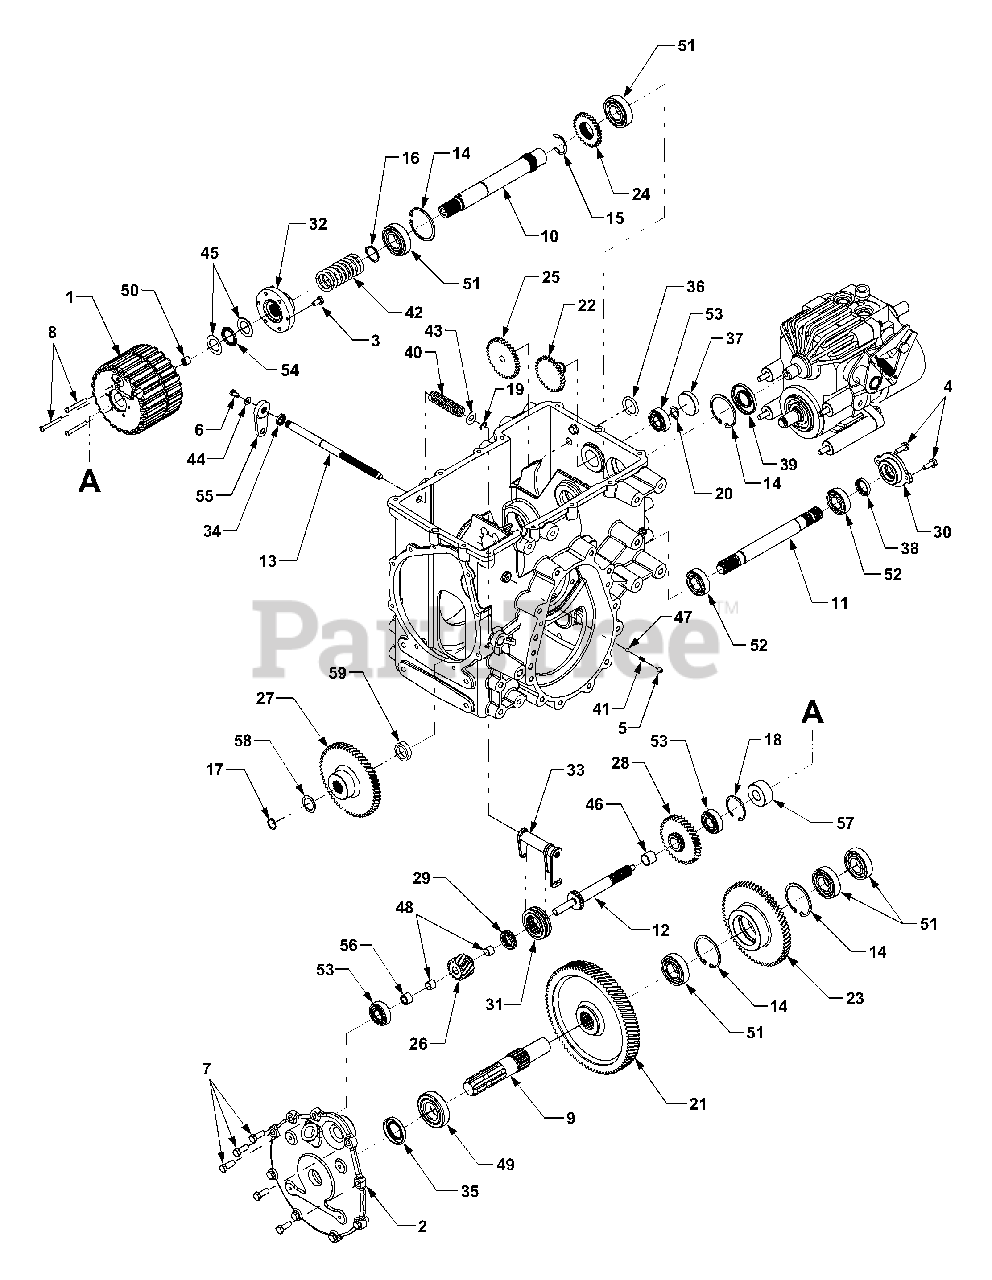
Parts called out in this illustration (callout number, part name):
1	Clutch Assembly, PTO
2	Housing, Rear
3	Screw, Hex Cap Lock, 1/4-20 x .62
4	Screw, Hex Wash Hd, 5/16-18 x .875 GR5
5	Screw, Cup Set, 5/16-18 x 3/8
6	Screw, Hex Cap, 1/4-20 x .5 GR5
7	Screw, Hex Cap Lock, 3/8-16 x 1.0 GR5
8	Screw, Round Hd, 6mm x 40mm
9	Shaft, 540 PTO
10	Shaft, Input
11	Shaft, 2000 PTO
12	Shaft, PTO Back
13	Shaft, PTO Actuator
14	Ring, Retaining
15	Ring, Retaining
16	Ring, Retaining
17	Ring, Retaining
18	Ring, Retaining
19	Ring, Retaining
20	Ring, Retaining
21	Gear, 540 PTO: 81T
22	Gear, Auxiliary Drive Idler: 28T
23	Gear, 2000 PTO: 61T
24	Gear, Auxiliary Drive Pinion: 28T
25	Gear, Auxiliary Drive: 32T
26	Gear, 540 PTO Pinion: 14T
27	Gear, 2000 PTO Pinion: 54T
28	Gear, 2000 PTO Pinion: 34T
29	Gear, Spline Coupling
30	Cover, 2000 PTO
31	Collar, 2 Speed
32	Coupling, PTO
33	Actuator, PTO
34	Seal, Oil
35	Seal, Oil
37	Plug, Oil
38	Seal, Oil
39	Seal, Oil
40	Spring, Compression
41	Spring, Detent
42	Spring, Compression
43	Washer, Flat, .56 x 1.0 x .040
44	Washer, Flat, .25 x .630 x .0515
45	Washer, Thrust, 1.007 x 1.542 x .03
46	Bearing, Sleeve, 20mm x 23mm x 20mm
47	Ball, Detent
48	Bearing, Sleeve, 13mm x 15mm x 10mm
49	Bearing, Ball
50	Bearing, Needle
51	Bearing, Ball
52	Bearing, Ball
53	Bearing, Ball
54	Bearing, Needle Thrust
55	Arm, PTO Select
56	Spacer, 13mm x 20mm x 14mm
57	Spacer, .80 x 1.85 x .855
58	Washer, Flat, .865 x 1.145 x .03
59	Spacer, .980 x 1.25 x .420
